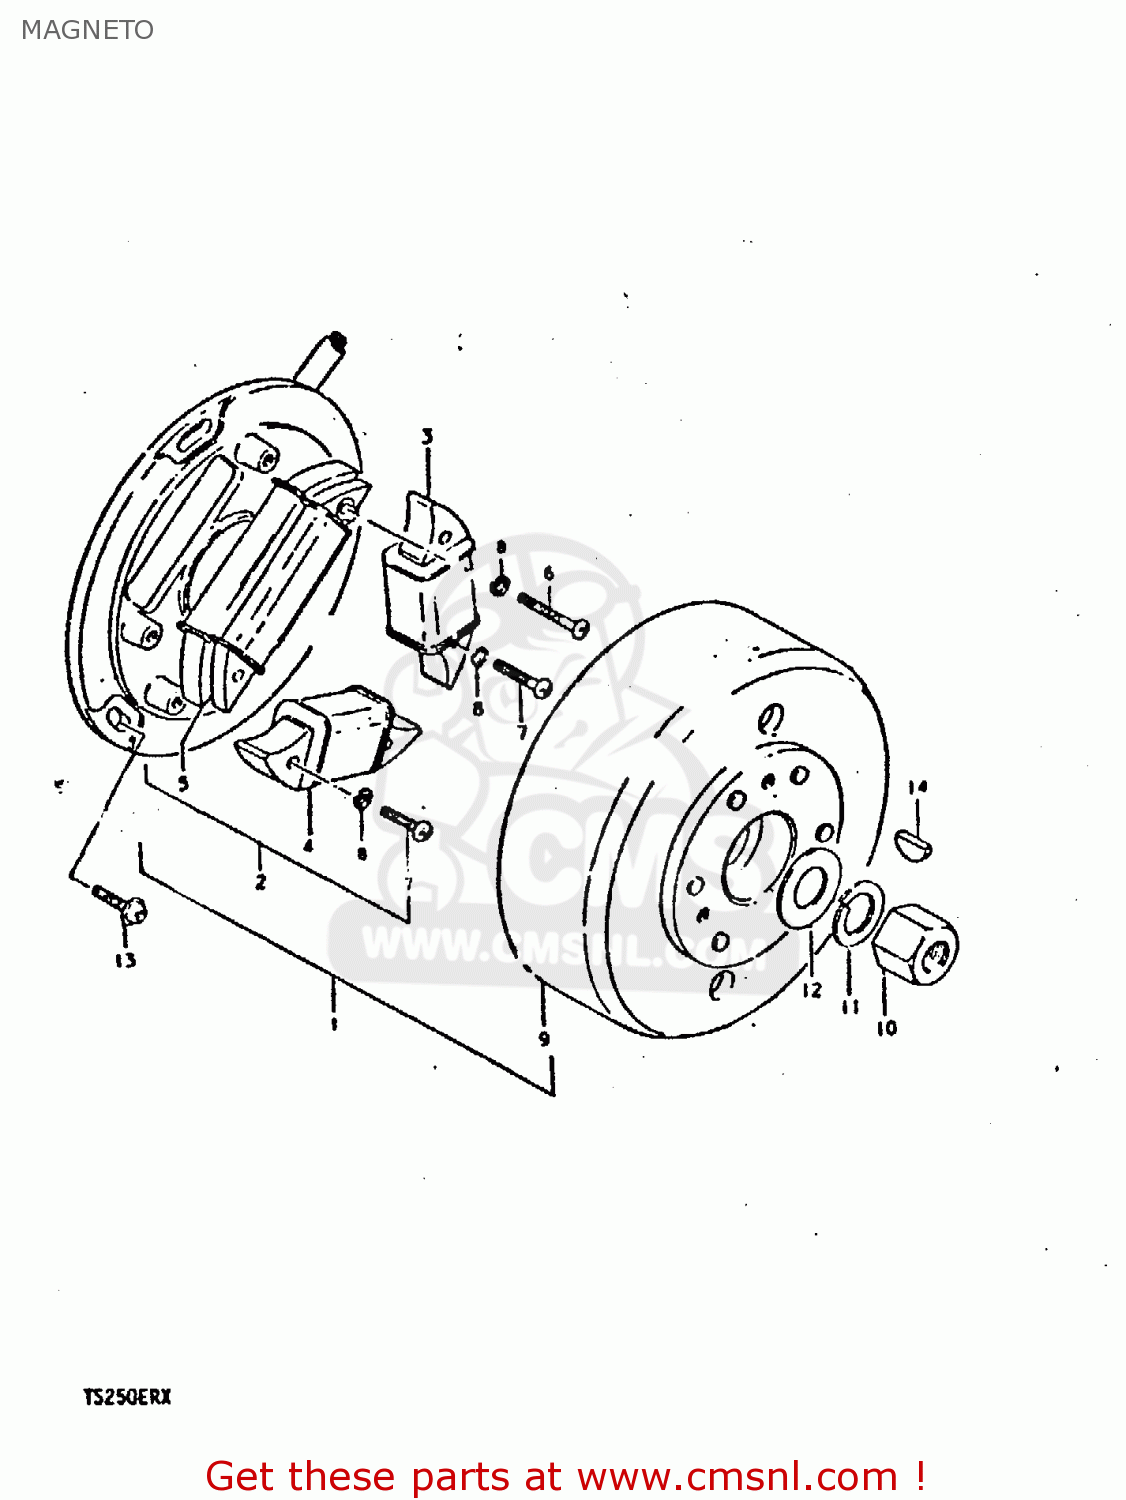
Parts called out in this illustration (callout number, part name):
1	MAGNETO ASSEMBLY
2	STATOR ASSEMBLY
3	COIL,LIGHTING
4	COIL,CHARGING
5	COIL,IGNITION
6	SCREW
7	SCREW 5X20
8	LOCK WASHER
9	ROTOR,FLYWHEEL
10	NUT
11	LOCK WASHER
12	WASHER(14X27X3)
13	SCREW(5X14)
14	KEY 4MM
